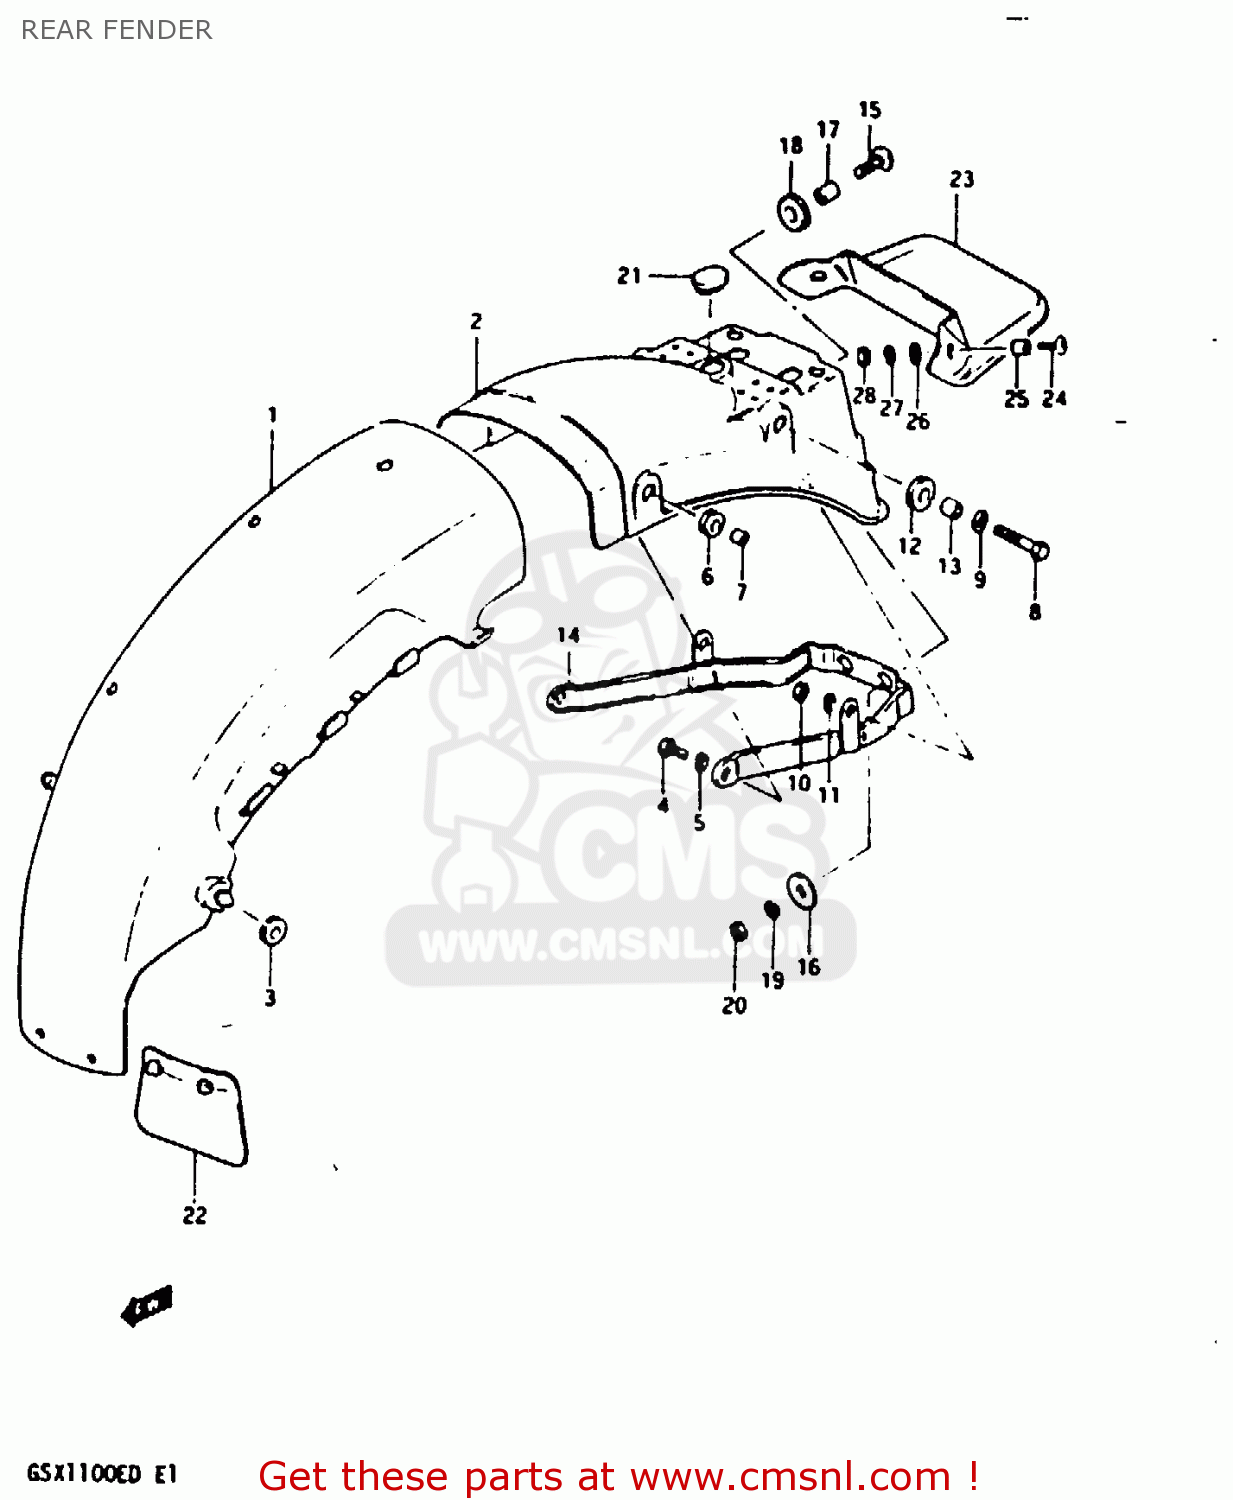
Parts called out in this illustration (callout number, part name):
1	FENDER,REAR
2	BODY,RR FENDER RR
3	CUSHION
4	BOLT
5	LOCK WASHER
6	CUSHION
7	SPACER(6.1X9X7.5)
8	BOLT
9	WASHER
10	NUT
11	LOCK WASHER
12	CUSHION
13	SPACER (8.2X12X7.5)
14	REINFORCEMENT,REAR FENDER
15	SCREW
16	WASHER(6,5X22X1.6)
17	SPACER (6.1X9X9)
18	CUSHION
19	LOCK WASHER
20	NUT
21	CAP
22	GUIDE,RR FENDER MUD
23	EXTENSION,REAR FENDER
24	SCREW (6X15)
25	SPACER(6.2X8.3X5.7)
26	WASHER(6.5X18X1)
27	LOCK WASHER
28	NUT
